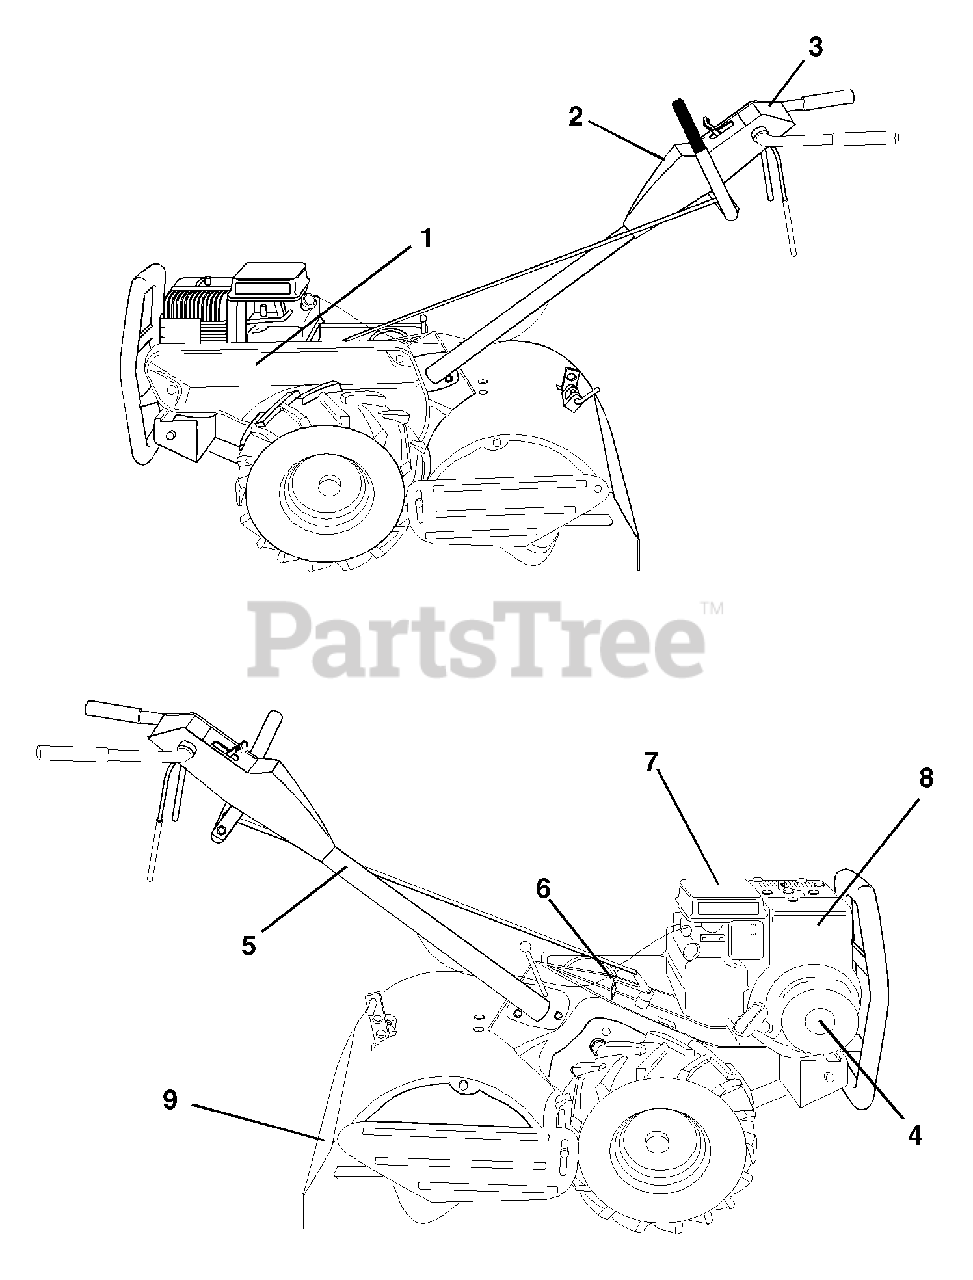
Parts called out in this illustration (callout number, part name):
1	Decal, Logo
2	Decal, Logo
3	Decal, Logo
4	Decal, 5.5 HP
5	Decal, Hand Placement
6	Decal, Shift Indicator
7	Decal, Caution
8	Decal, Briggs & Stratton
9	Decal, Warning, Rotating Tines
